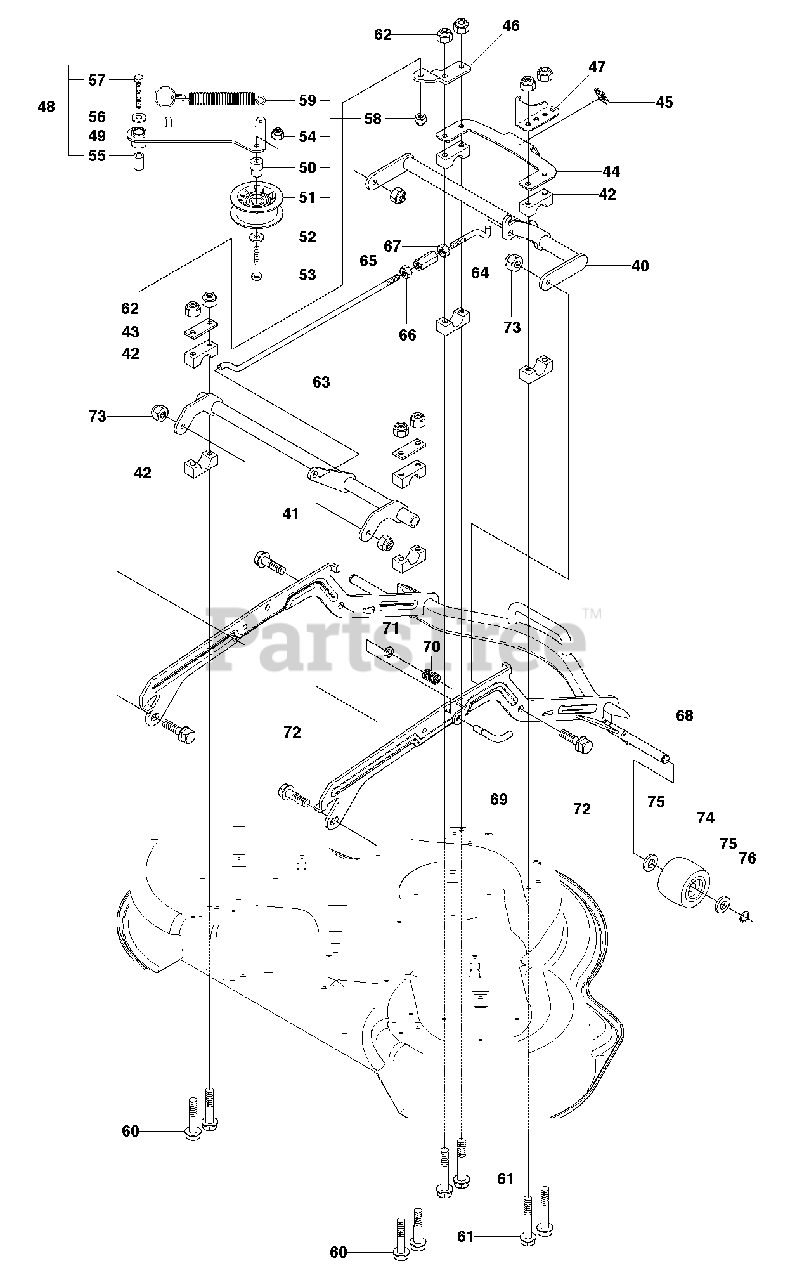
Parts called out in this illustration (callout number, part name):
51	PULLEY
52	SPACER
53	SCREW
54	LOCKNUT M8
55	BUSHING
56	SPACER
57	SCREW
58	LOCKNUT M8
59	SPRING
62	LOCKNUT M8
73	LOCKNUT M8
74	DECK ROLLER, FRONT
76	RETAINING RING SGA 15
